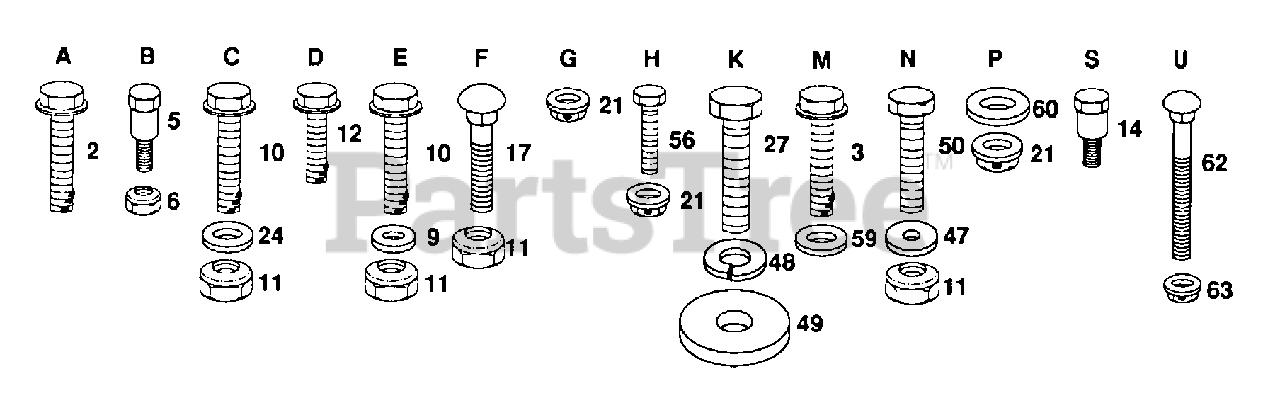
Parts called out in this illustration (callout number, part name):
2	SCREW
3	SCREW GTV
9	WASHER
12	SCREW LT
17	BOLT
21	PAL NUT LT
24	WASHER
27	BOLT
47	WASHER
48	LOCKWASHER
49	WASHER
50	BOLT
56	SCREW SPECIAL
59	WASHER
60	WASHER PM
62	BOLT
